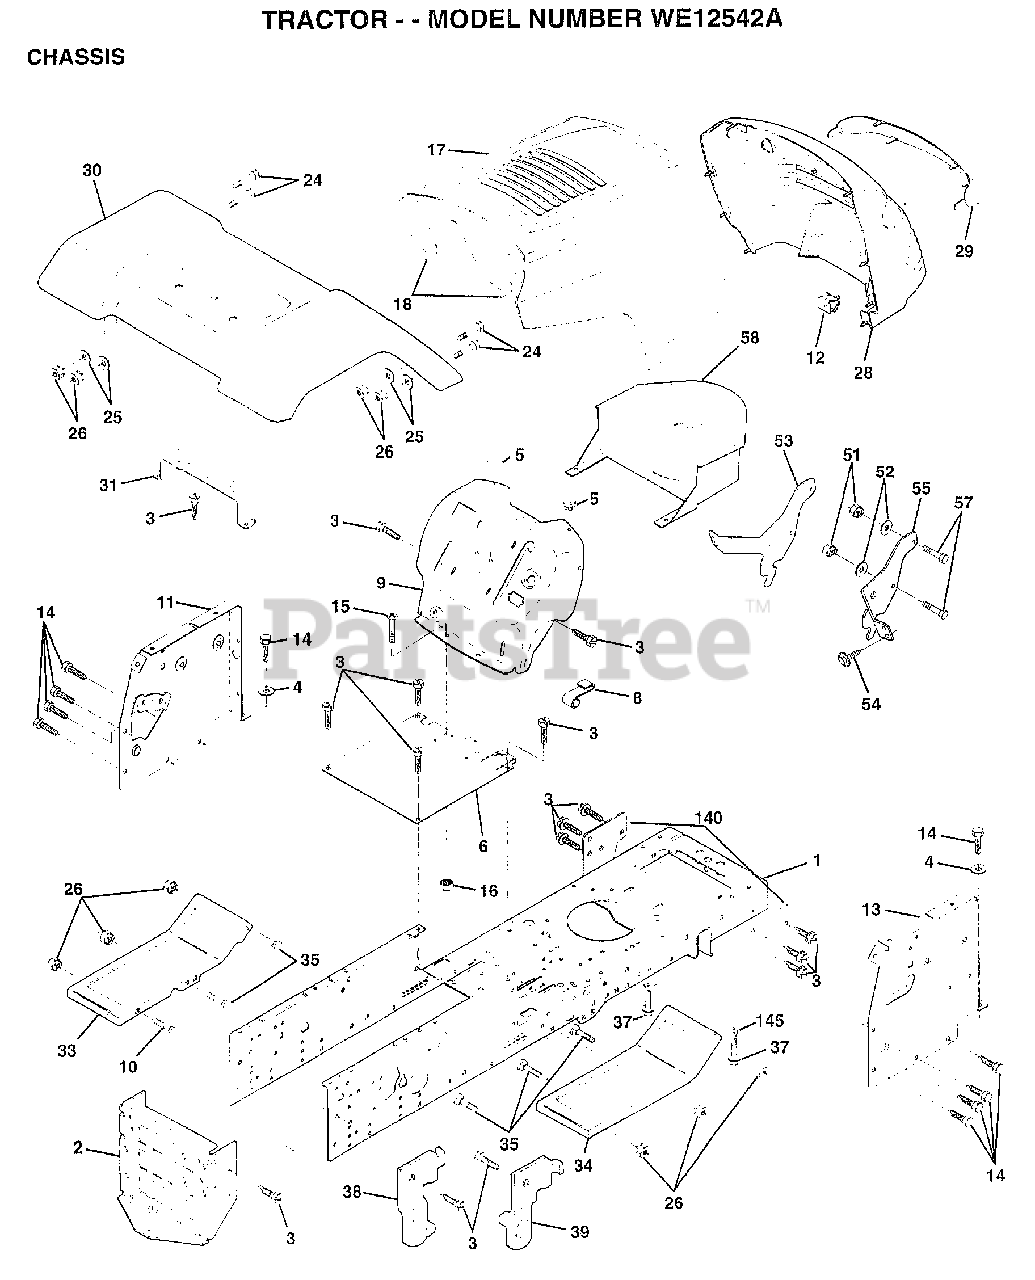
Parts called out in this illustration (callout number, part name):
1	CHASSIS ASM
3	SCREW
4	WASHER
5	BUMPER-HOOD/DASH
6	SADDLE-SILKSCREEN
8	CLIP.RETAINER
9	DASH.SILKSCREENED
11	"PANEL-DASH,LH"
12	CLIP.TINNERMAN
14	SCREW LT
15	SCREW
17	HOOD.STEEL.ASSY
19	BOLT
25	WASHER
26	NUT
28	GRILLE-MS428
29	LENS GRILLE
31	BRKT FENDER
33	FOOTREST.LH.PERF.
34	FOOTREST.RH.PERF.
35	BOLT
37	SCREW LT
38	BRACKET ASM LH
39	BRACKET ASM RH
51	NUT
52	WASHER
53	BRACKET.GRILLE.LH
55	BRACKET.GRILLE.RH
58	AIR DUCT
140	BRKT SUSPENSION
145	"ROD POVOT,CHASSIS"
